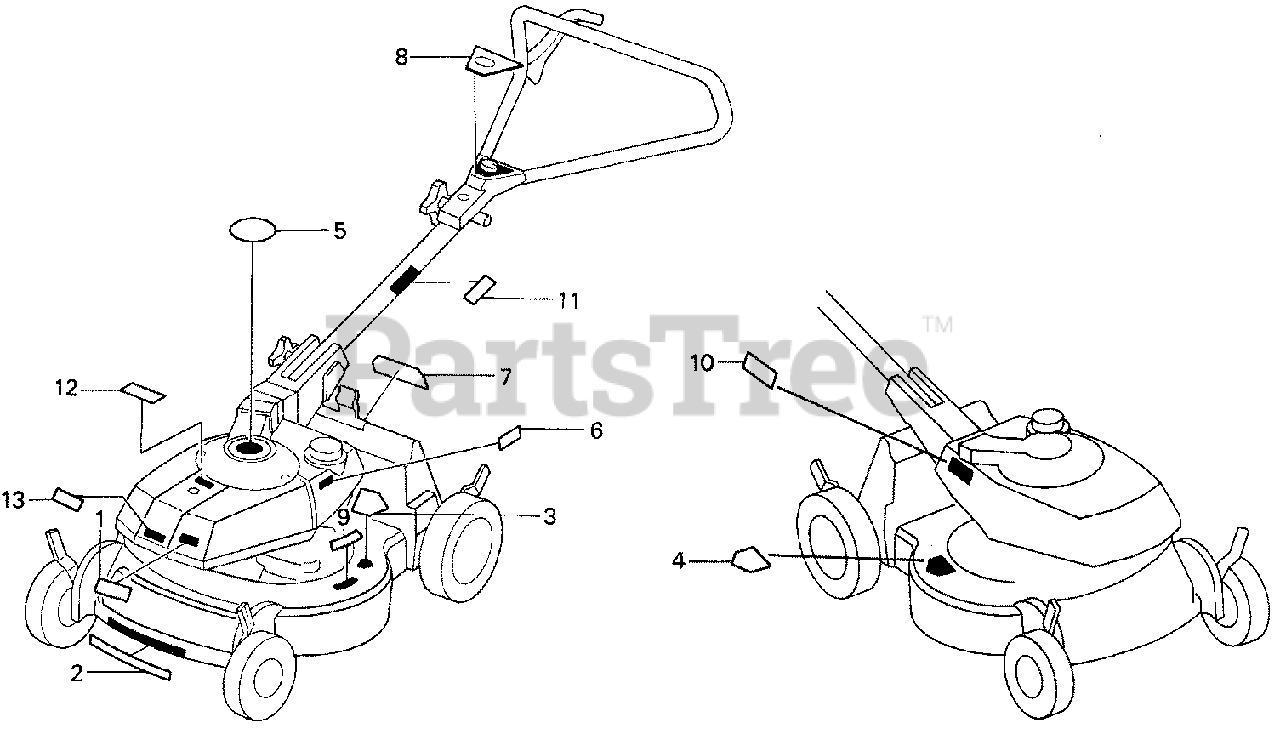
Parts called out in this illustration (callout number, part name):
1	MARK, TOP COVER
1	MARK, TOP COVER (NOT AVAILABLE)
2	LABEL A, HOUSING CAUTION
3	LABEL B, HOUSING CAUTION (ENGLISH)
4	CAUTION C, HOUSING
5	CAUTION, OPERATOR (ENGLISH)
6	LABEL, FUEL CAUTION (ENGLISH) (NOT AVAILABLE)
7	LABEL, DISCHARGE GUARD CAUTION (ENGLISH) (NOT AVAILABLE)
7	LABEL, DISCHARGE GUARD CAUTION (NOT AVAILABLE)
8	MARK, SWITCH (ENGLISH) (NOT AVAILABLE)
9	LABEL, PLUG & OIL CAUTION (ENGLISH) (NOT AVAILABLE)
10	LABEL, RECOIL OPERATOR CAUTION (NOT AVAILABLE)
11	MARK, GRASS BAG CAUTION (ENGLISH) (NOT AVAILABLE)
12	LABEL, AIR CLEANER CAUTION (ENGLISH) (NOT AVAILABLE)
13	MARK, TYPE (PD)
